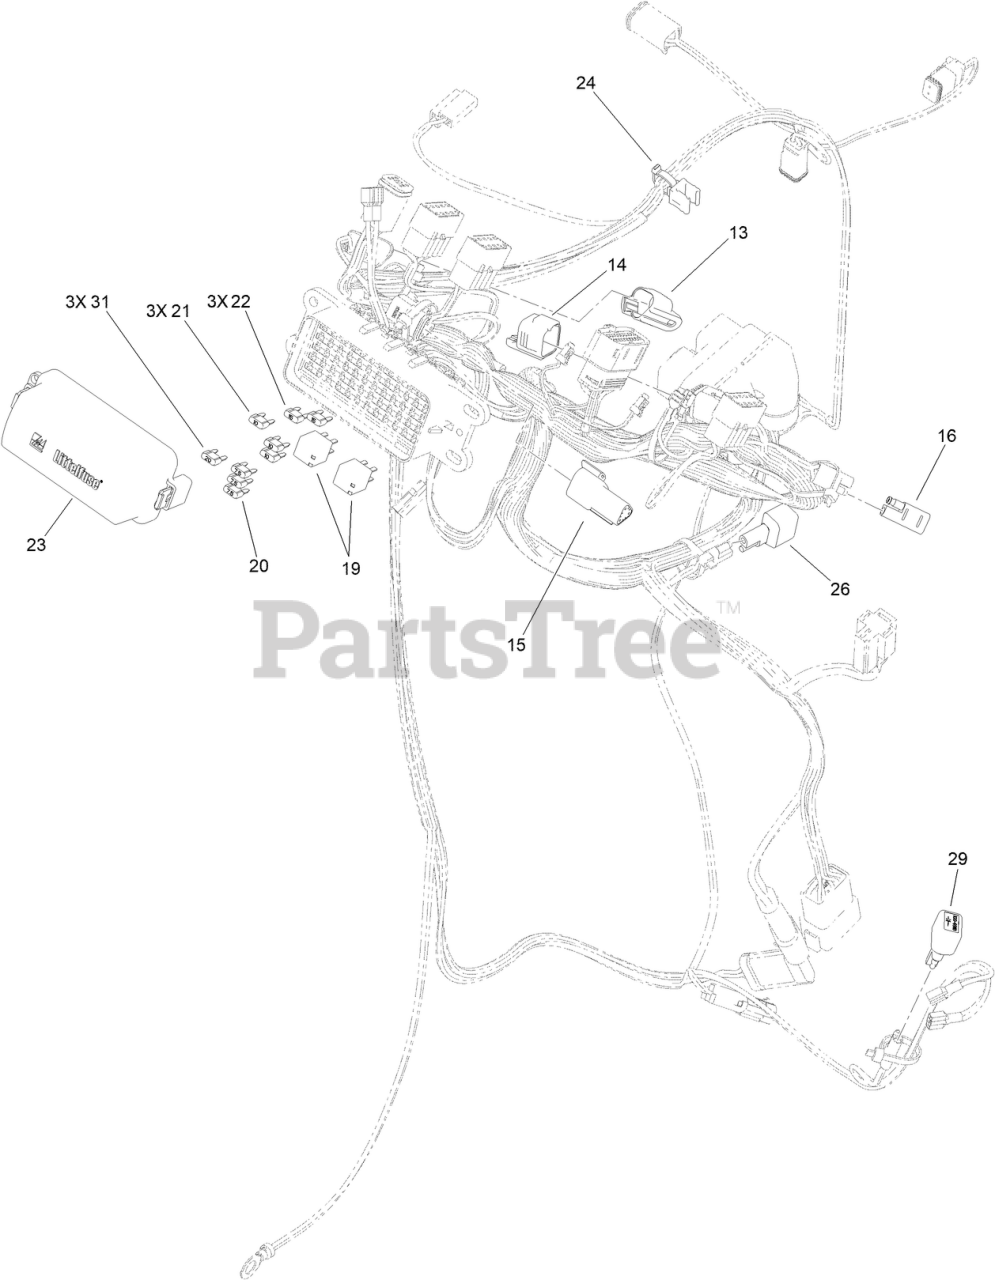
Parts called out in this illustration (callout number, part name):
13	CAP-PLUG, 3 WAY
14	CAP-PLUG, 6 WAY
15	RESISTOR-120 OHM
16	CAP-PLUG
19	RELAY-MICRO
20	FUSE-MINI BLADE, 7.5 AMP
21	FUSE-MINI BLADE, 10 AMP
22	FUSE-MINI BLADE, 15 AMP
23	COVER-LITTELFUSE, PDM 60F
24	CLIP-EDGE
26	RESISTOR-75 OHM
31	FUSE-MINI BLADE, 20 AMP
